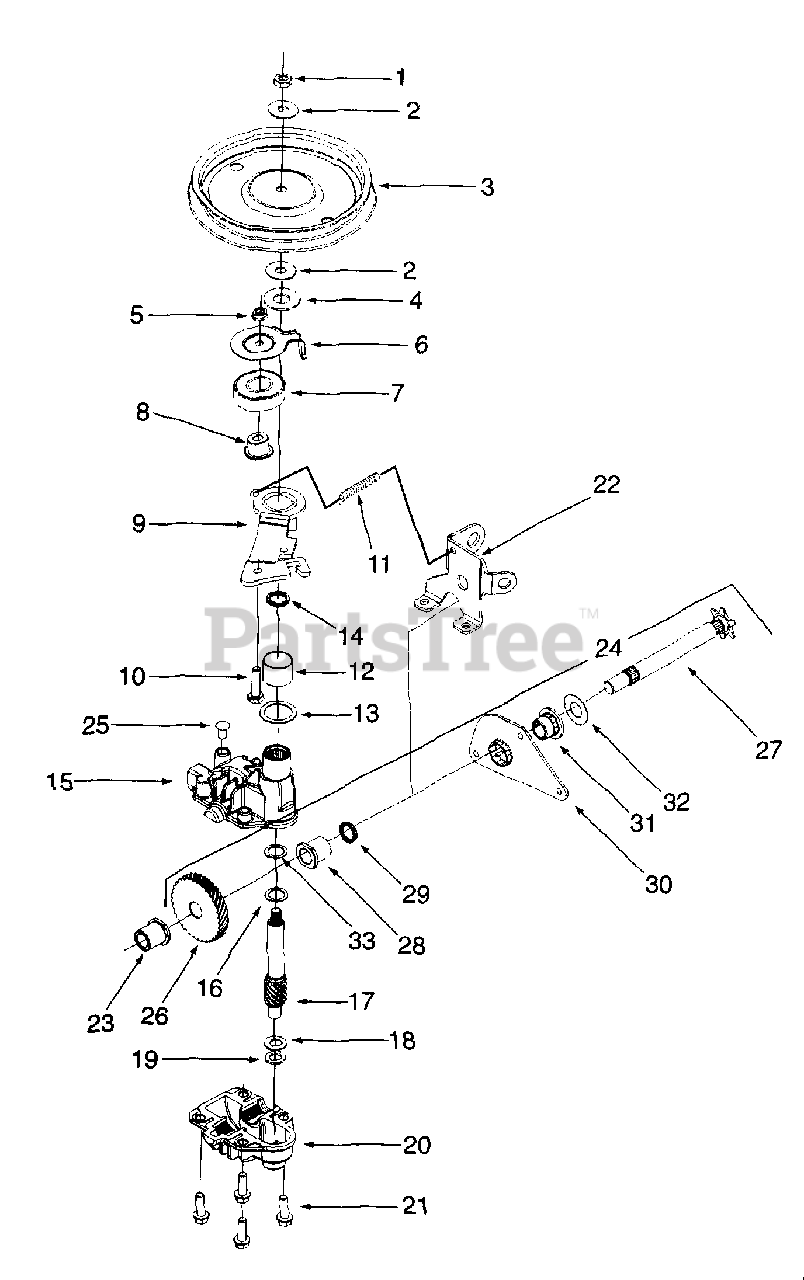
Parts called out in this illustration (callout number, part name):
1	Hx. Jam Nut 5/16-24
2	Bell Wash. .325 x .930 x .045
3	Pulley
4	Fl. Wash. .510 x 1.120 x .060
5	Hx. Jam Nut 1/4-28
6	Belt Keeper
7	Bearing
8	Flange Spacer
9	Idler Bracket Assembly
10	Hx. Cap Scr. 1/4-28 x 1.00 Gr. 5
11	Extension Spring
12	Bearing Sleeve
13	Fl. Wash. .885 x 1.145 x .030
14	Oil Seal
15	Upper Housing Assembly
16	Thrust Wash. .504 x .700 x .030
17	Pinion Shaft 10T.
18	Thr. Wash .3/8 x .70 x .030
19	Thr. Wash. .388 x .625 x .062
20	Lower Housing Assembly
21	Hx. Scr. 1/2-20 x .75
24	Shaft Assembly
26	Gear 34 T.
27	Output Shaft 6 T.
28	Flange Bearing
29	Oil Seal
30	Pivot Bracket
31	Flange Bearing
32	Wash. Fl. .508 I.D. x 1.00 O.D. x .020
33	Bearing
